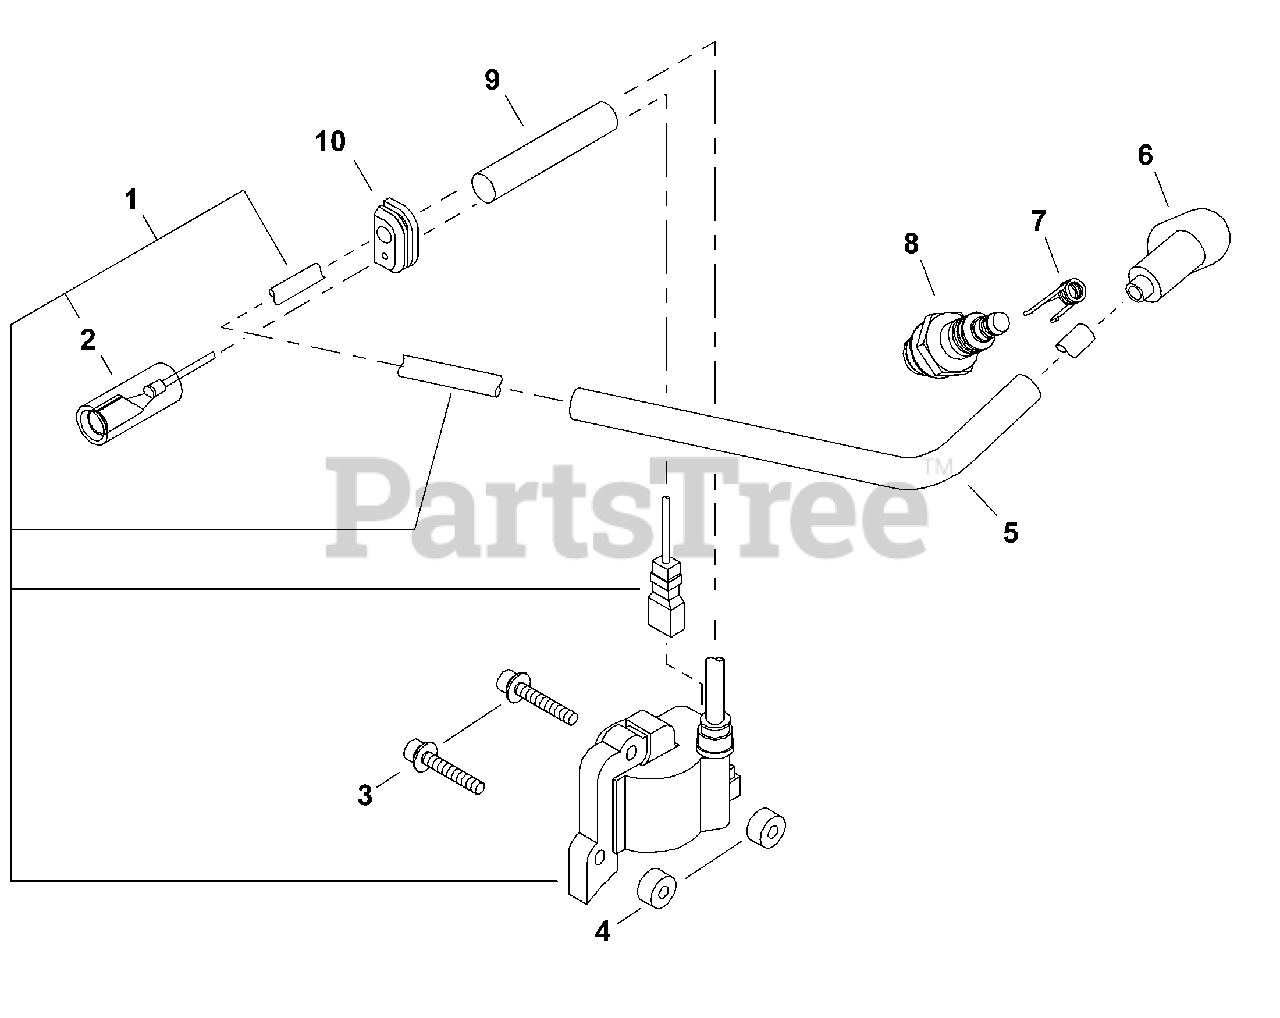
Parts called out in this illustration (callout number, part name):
1	COIL ASSY, IGNITION
3	BOLT M4×26
4	INSULATOR 4.2×11×6
5	TUBE, INSULATOR
6	CAP, SPARK PLUG
7	TERMINAL, SPARK PLUG
8	SPARK PLUG - CJ8
9	TUBE, IGNITION COIL
10	GROMMET
